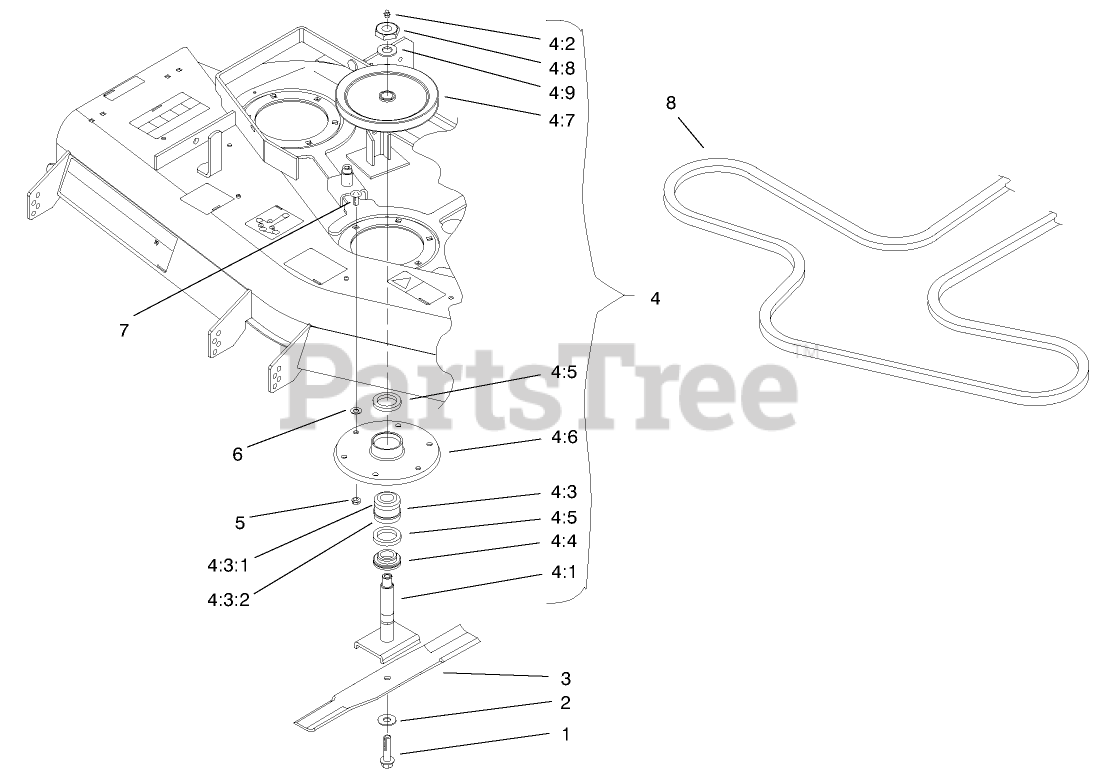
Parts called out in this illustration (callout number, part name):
1	BOLT-BLADE
2	Washer-Flat
3	BLADE-SAIL, EXTRA HIGH
4	Spindle Housing ASM
4:1	Shaft-Spindle
4:2	FITTING-GREASE
4:3	BEARING ASM
4:3:1	BEARING ASM
4:3:2	SPACER-SET, MATCHED
4:4	SPACER
4:5	SEAL-OIL
4:6	HOUSING-SPINDLE
4:7	Pulley & Hub
4:8	NUT-HEX
4:9	WASHER
5	NUT-HF
6	WASHER-FLAT
7	SCREW-CARR
8	BELT-DECK (52)
